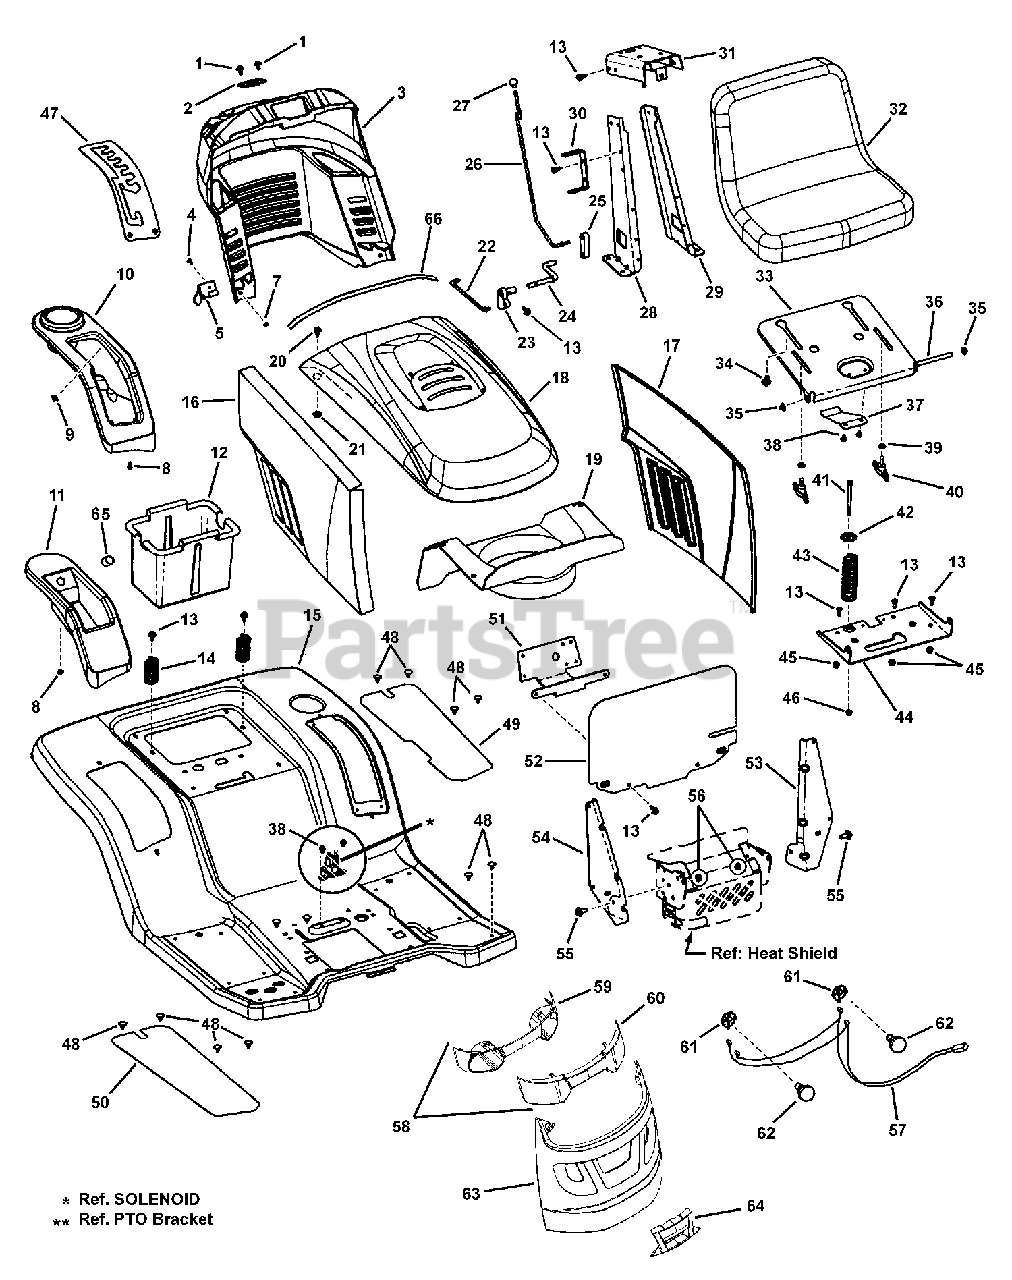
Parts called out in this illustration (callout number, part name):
1	SCREW, 1/4-20 x 5/8" Hex Washer Self-Tap
2	BEARING, Steering
3	CONSOLE, Tractor
4	SCREW, #10-24 x 1/2" Hex Washer Head (Taptite)
5	HOOD GUIDE, RH
7	NUT, #10-24 Hex Nyloc, BZ
8	SCREW, 1/4-20 Thread Cutting
9	CUTTING HEIGHT INDICATOR
10	POD, W/ DETENT
11	POD, W/ COMPARTMENT
12	CONTAINER, Battery
13	CAPSCREW, 5/16-18 Hex Washer Face
14	SPRING, Compression 2.43 Length
15	SEAT DECK
16	PANEL, Hood RH Side
17	PANEL, Hood LH Side
18	HOOD, w/ Louvers
19	AIR DUCT, Plastic
20	SCREW, 1/4-20 x 5/8" Hex Whiz Lock Flange, Black
21	NUT, 1/4-20 Large Hex Flange Lock, Black
22	LINK, Cruise Rod
23	WELDMENT, Latch Arm
24	ROD, Pivot Cruise
25	CHANNEL, CRUISE
26	ACTUATOR, CRUISE
27	PULL KNOB, 1/4-20 Thread
28	BRACKET, Dash Support, RH
29	BRACKET, Dash Support, LH
30	BRACKET, Support Cruise
31	WELDMENT, Clutch Rod Support
32	SEAT, Hi Back
33	SUPPORT, Seat
34	BOLT, 5/16-18 Shoulder
35	CAP, Push On
36	ROD, Pivot
37	SPRING, Leaf
38	SCREW, 1/4-14 x 3/8" Hex Washer Self-Tap
39	WASHER, .34 x .62 x 16 GA Flat
40	WING BOLT, 5/16-18 UNC 2A
41	BOLT, 1/4-20 x 3.652 2A Shoulder
42	WASHER, Cup, 1.50 OD x 0.344 ID
43	SPRING, Compression, 4.57 Free Length
44	BRACKET, Seat Pivot
45	NUT, 5/16-18 Hex Nyloc
46	NUT, 1/4-20 Hex Flange Lock
47	PLATE, Index
48	FASTENER, Panel
49	MAT, Left
50	MAT, Right
51	STIFFENER, Steering
52	BULKHEAD
53	HOOD, Pivot LH
54	HOOD, Pivot RH
55	BOLT, 3/8-16 Shoulder
56	NUT, 3/8-16 Hex Flange Lock, NC
57	HARNESS, Headlight, TCT, 1/4 Terminals
58	HEADLIGHT ASSY, (Includes #'s 59, 60, 61, & 62)
59	REFLECTOR, Headlight
60	LENS, Headlight
61	SOCKET, Light
62	BULB, 12.8V (1141)
63	GRILLE, Snapper
64	INSERT, Light Bar
65	HOLE PLUG, Plastic
66	STRIP, Trim
